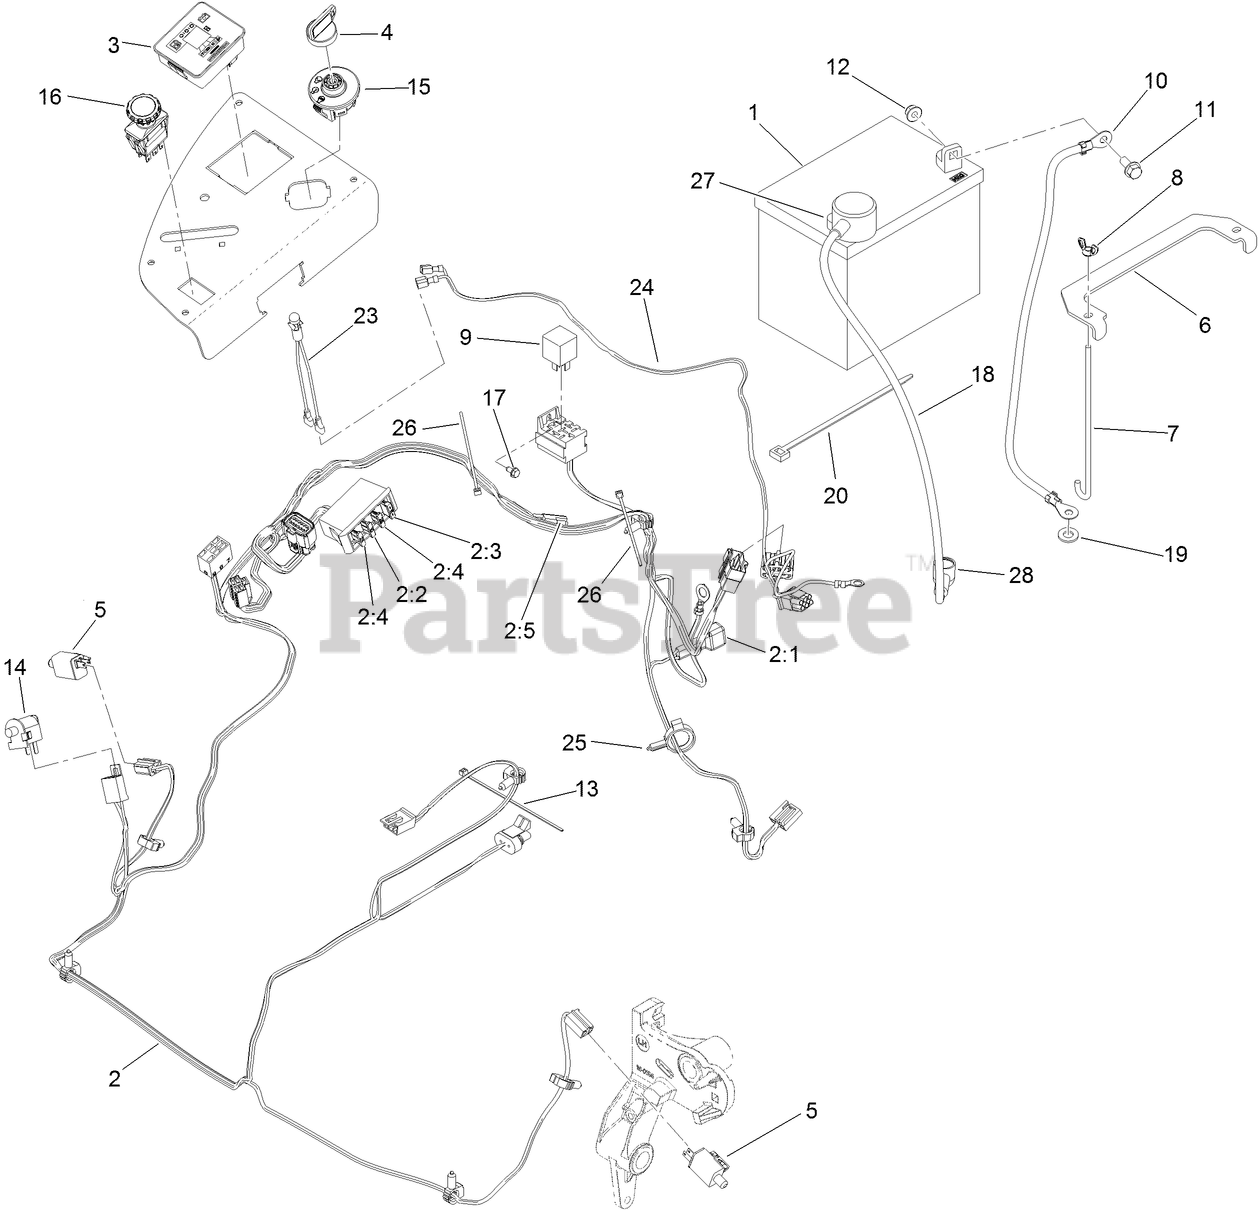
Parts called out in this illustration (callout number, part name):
1	BATTERY-DRY
1	BATTERY (300 CCA, WET)
2	HARNESS-WIRE, MAIN
2:2	FUSE-BLADE, 10 AMP
2:3	FUSE-BLADE, 15 AMP
2:4	FUSE-BLADE, 25 AMP
2:5	CAP-PLUG
3	FUEL/HOUR METER ASM
4	KEY-IGNITION
5	SWITCH
6	STRAP-TIE DOWN, BATTERY
7	BOLT-HOLDDOWN
8	WINGNUT
10	CABLE-BATTERY, NEGATIVE
11	SCREW-HHF
12	NUT-HF, NI
13	TIE-CABLE
14	SWITCH-BAIL
15	SWITCH-IGNITION
16	SWITCH-PTO, 10 AMP
17	SCREW-HWH
18	CABLE-BATTERY, POSITIVE
19	WASHER-FLAT
20	TIE-PLASTIC
23	INDICATOR-LED, RED
24	HARNESS-LIGHT, INDICATOR
25	CLAMP-HOSE
26	TIE-CABLE
27	INSULATOR-BATTERY
28	INSULATOR-SOLENOID
